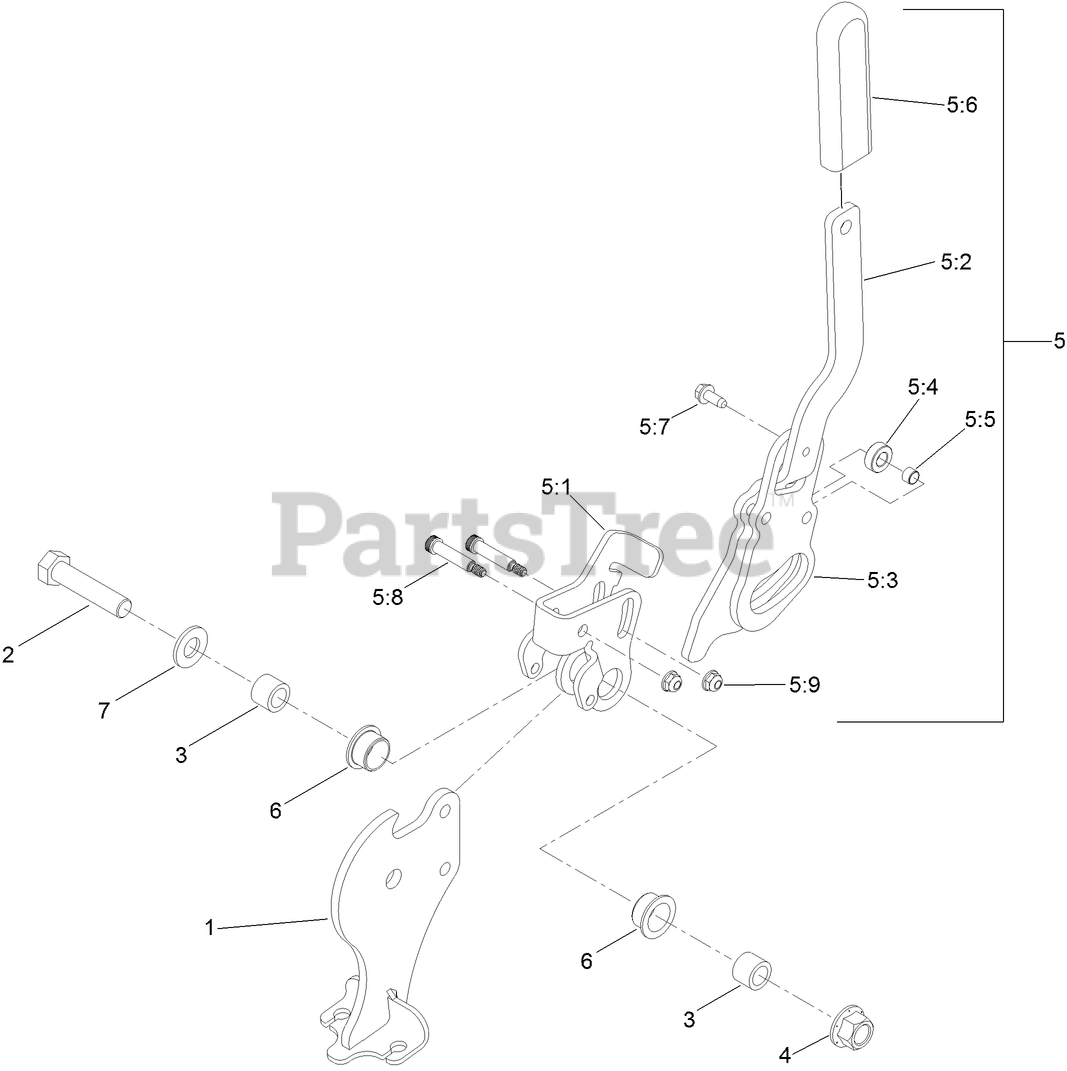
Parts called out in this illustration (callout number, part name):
1	BRAKE PIVOT ASM
2	SCREW-HH
3	SPACER
4	NUT-LOCK
5	HANDLE ASM
5:1	BELLCRANK-BRAKE
5:2	HANDLE-BRAKE
5:3	PLATE-HANDLE
5:4	ROLLER-BRAKE
5:5	BEARING-SLEEVE
5:6	GRIP-LEVER
5:7	SCREW-HWH
5:8	SCREW-SHOULDER
5:9	NUT-HF
6	BUSHING-FLANGE
7	WASHER-FLAT
